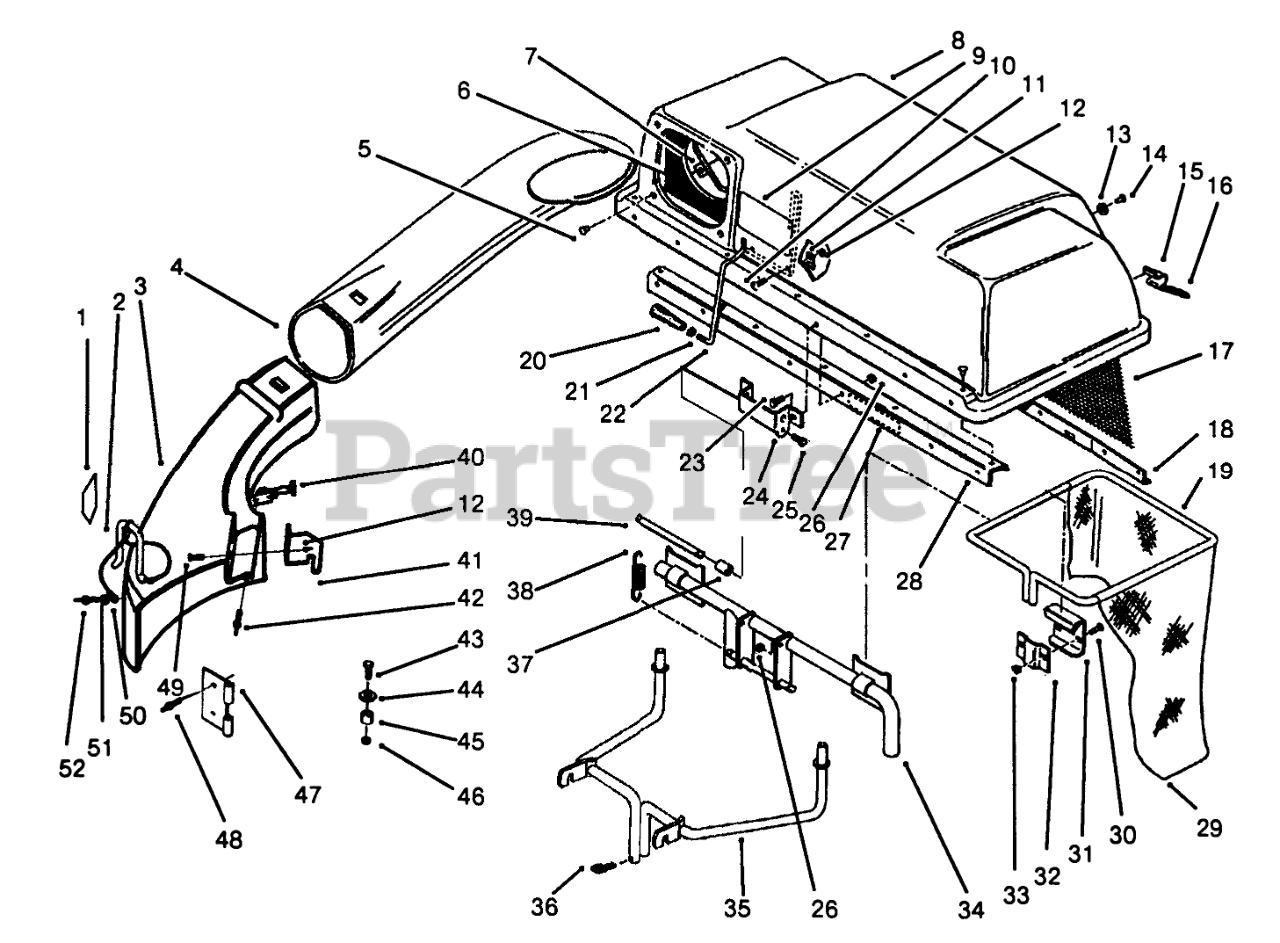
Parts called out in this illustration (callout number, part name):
1	DECAL-DANGER
2	PIN-LOCKING, CHUTE
3	ELBOW-BAGGER, 38 INCH
4	CHUTE-BAGGER
5	Hairpin
6	SEAL-CHUTE
7	CLAMP-SEAL
8	TOP-BAGGER
9	DECAL
10	Screw
11	Clip
12	Nut
13	Washer
14	RIVET-BLIND
15	Latch-Bag
17	SCREEN-BAGGER B
18	SUPPORT-SCREEN B
19	Bag Frame
20	HANDLE-TAPERED
21	Nut
22	FEELER-FILL, BAG
23	BOLT
24	HINGE-BAG TOPB
25	Bolt
26	NUT
27	DECAL-CAUTION
28	Bagger-Stiffener
29	BAG-18" DEPTH
30	Bolt
31	Bag Hanger
32	Clamp
33	Nut
34	FRAME ASM
35	ASM-QUICK ATTACH B
36	Hairpin
37	SPACER
38	SPRING-EXTENSION
39	PIN-SPRING
40	Latch-38"
41	LATCH-BAGGER ELBOW
42	NUT-LOCK, NI
43	BOLT
44	Washer
45	SPACER
46	NUT
47	BRACKET-MOUNTING, CHUTE
48	RIVET-BLIND
49	Bolt
50	LANYARD
51	NUT-LOCK, NI
52	RIVET-BLIND
